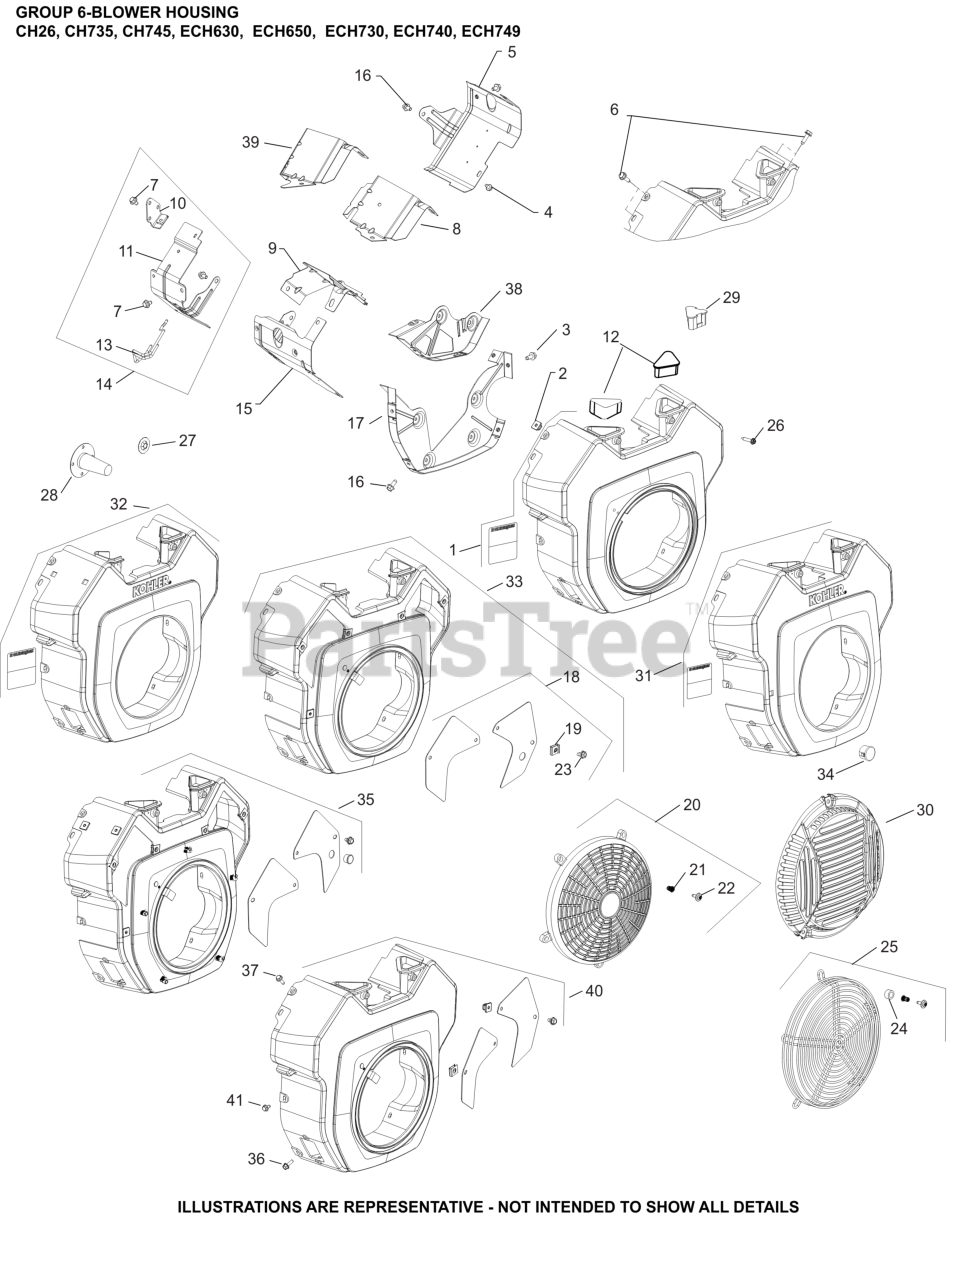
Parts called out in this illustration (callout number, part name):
1	KIT, BLOWER HOUSING
1	HOUSING, BLOWER
3	SCREW, THREAD FORMING
4	SCREW, THREAD FORMING
5	KIT, RIGHT BARREL
8	BAFFLE, VALLEY #1 CYLINDER
9	BAFFLE, VALLEY #2 CYLINDER
15	BAFFLE LEFT BARREL
16	SCREW, THREAD FORMING
17	PLATE, BACKING
17	KIT, BACKING PLATE
20	KIT, FIXED GUARD
21	INSERT, THREADED (M5)
22	SCREW, SEMS
29	COVER, BLOWER HOUSING
